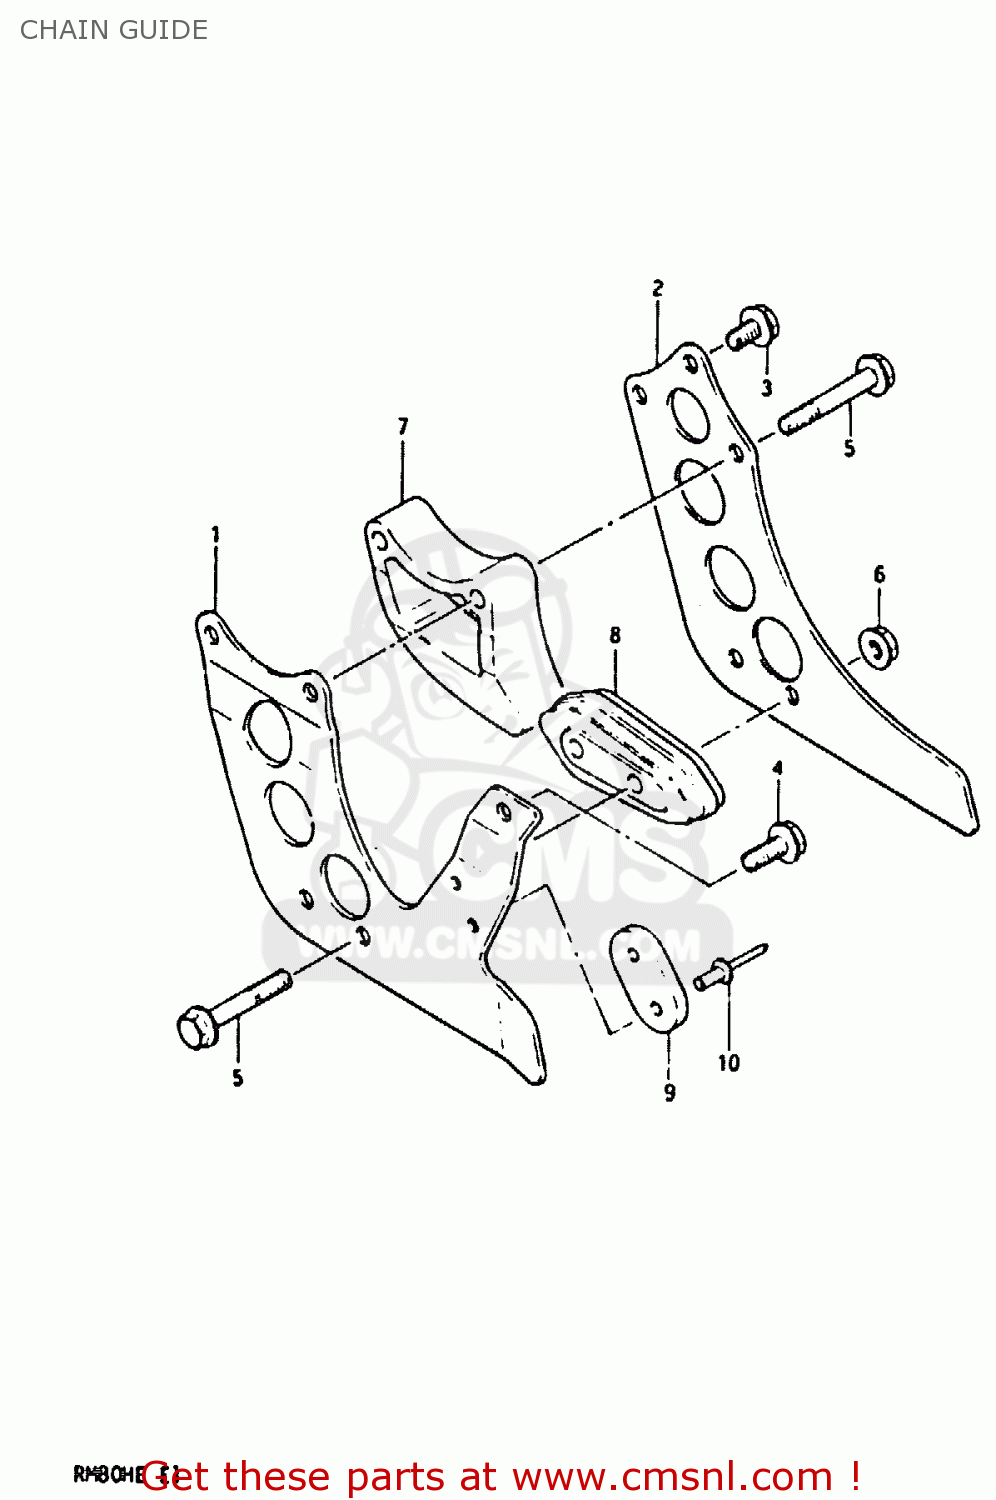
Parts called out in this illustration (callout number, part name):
1	PLATE,OUTER
2	PLATE,INNER
3	BOLT
4	BOLT
5	BOLT
6	NUT
7	DEFENSE,CHAIN GUIDE UPR
8	DEFENSE,CHAIN GUIDE
9	PAD,CHAIN GUIDE
10	RIVET
